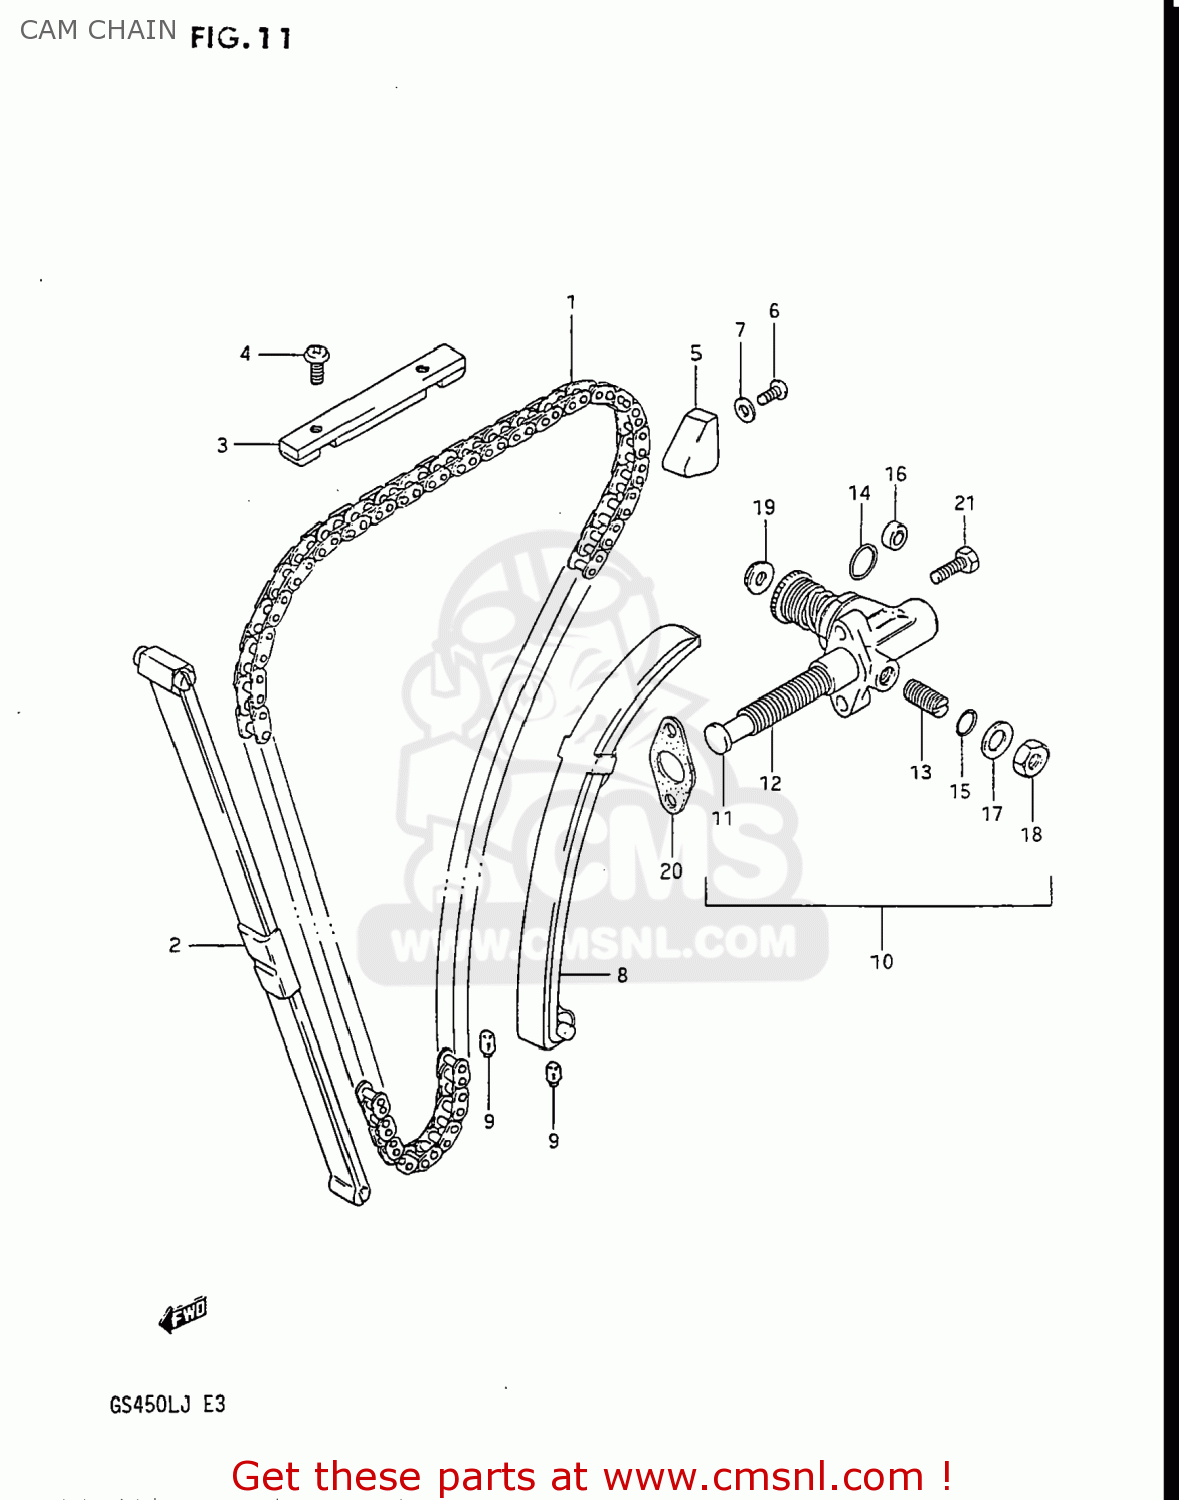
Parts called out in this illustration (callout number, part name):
1	CHAIN,CAMSHAFT DRIVE(120L)
2	GUIDE,CAM CHAIN NO.1
3	GUIDE,CAM CHAIN NO.3
4	SCREW
5	GUIDE,CAM CHAIN
6	BOLT 6X12
7	WASHER
8	TENSIONER,CAM CHAIN
9	CUSHION,CAM CHAIN TENSIONER
10	ADJUSTER ASSEMBLY,TENSIONER
11	ROD,PUSH
12	SPRING
13	SCREW,TENSIONER ADJUST
14	O RING(D:2.4,ID:20.8)
15	O RING(D:1.9,ID:5.7)
16	SEAL,OIL(10X16X4)
17	WASHER
18	NUT
19	NUT 6MM
20	GASKET,TENSIONER ADJUSTER (MCA)
21	SCREW
